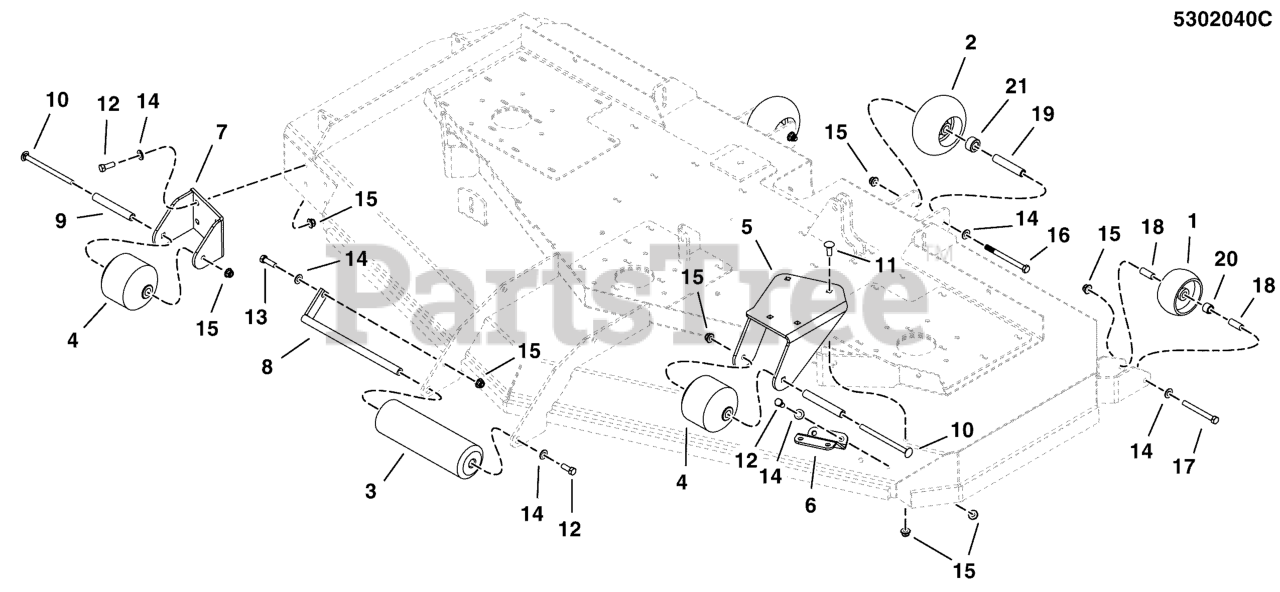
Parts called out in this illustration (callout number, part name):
1	WHEEL- 2.00 WIDE 3.88 DIA 0.531ID POLY
2	GAUGE WHEEL-2.70
3	ROLLER, DECK
4	ROLLER, SMALL
5	WELD, ANTI-SCALP BRACKET - RED
6	PLATE, ANTI-SCALP SUPPORT - RED
7	WELD, BRACKET, ANTI-SCALP - RED
9	SPACER, .38 X .63 X 4.31
10	BOLT, 3/8-16 X 5-1/2, CARRIAGE
11	BOLT, Carriage, 3/8-16 X 1
12	BOLT, 3/8-16 X 1" GD5 CZ
13	BOLT, 3/8-16 X 1-1/4" GD5 CZ
14	WASHER, 3/8 SAE
15	NUT, 3/8-16 HEX NYLOCK FLANGE
16	BOLT, 3/8-16 X 4-1/2" GD5 CZ
17	BOLT, 3/8-16 X 3-1/2" GD5 CZ
18	SPACER, .38 X .50 X 1.25, CZ
19	SPACER, .38 X .63 X 3.25, CZ
20	SPACER, .51 X .75 X .56, CZ
21	SPACER, .64 X 1.13 X .63, CZ
